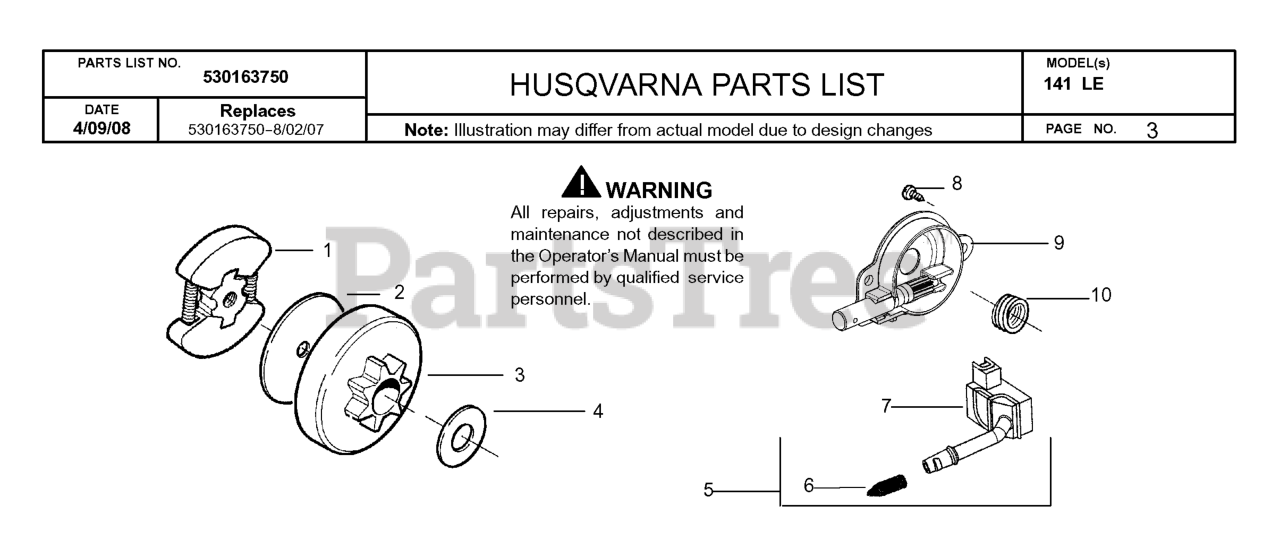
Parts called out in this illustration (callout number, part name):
1	CLUTCH ASSEMBLY
2	FRICTION DISC,CLUTCH 36/41
3	CLUTCH DRUM ASSY
4	THRUST WASHER
5	OIL PICKUP
6	SCREEN/FILTER
9	OILER ASS'Y 36/41
10	OILER GEAR 36/41
